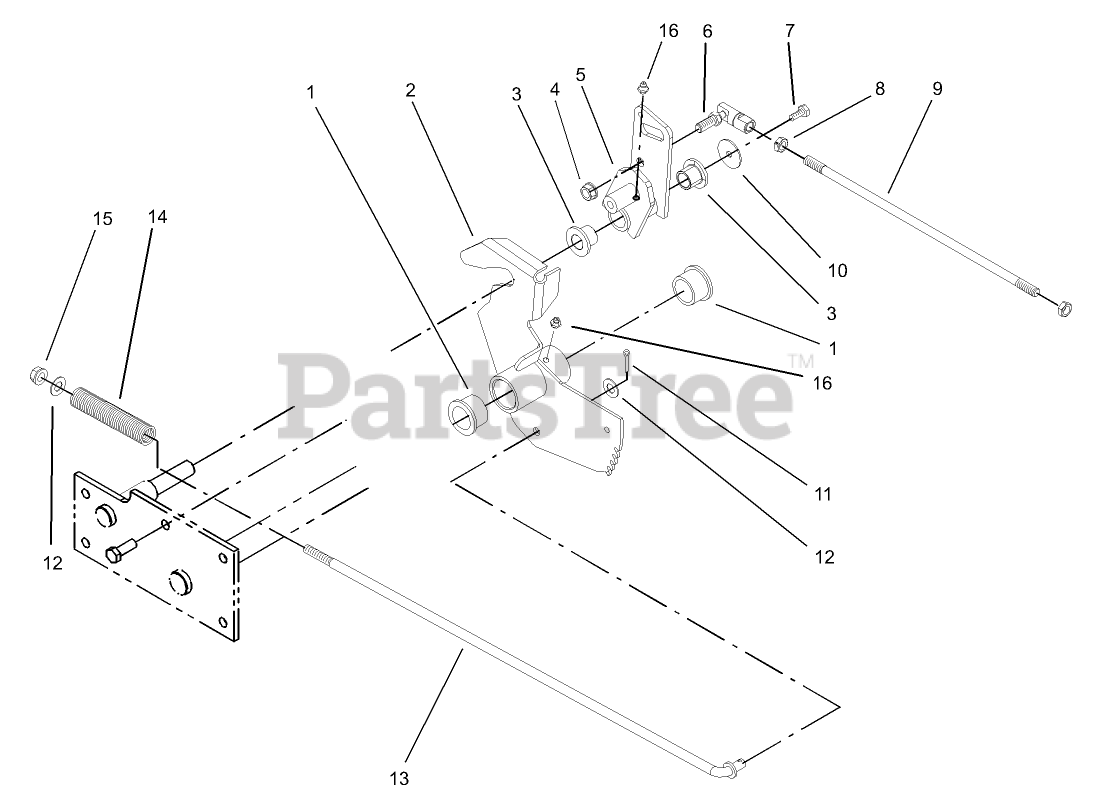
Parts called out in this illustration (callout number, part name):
1	BUSHING-FLANGED
2	PLATE-PIVOT, BRAKE
3	BUSHING
4	NUT-LOCK
5	PIVOT-HYDRO
6	END-TIE ROD, LH
7	SCREW-HH
8	NUT-HEX JAM, LH
9	ROD-PIVOT TO PEDAL
10	WASHER-FLAT
11	PIN-COTTER
12	WASHER-FLAT
13	ROD-BRAKE
14	SPRING-COMPRESSION
15	NUT-LOCK, NI
16	FITTING-GREASE
